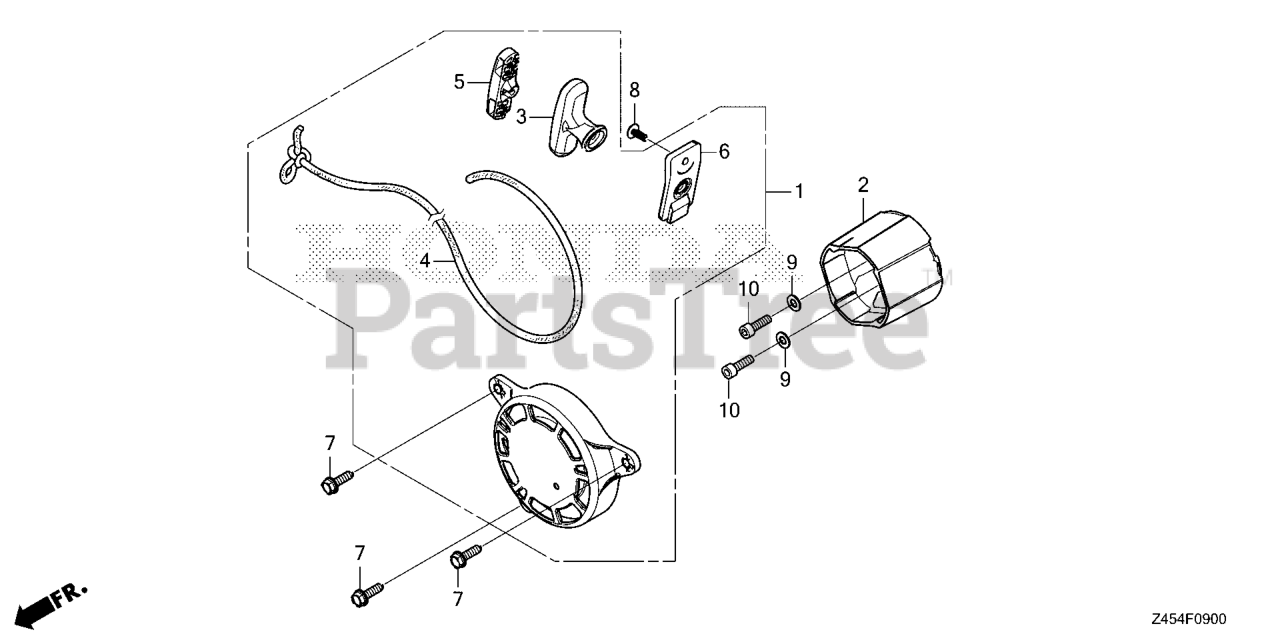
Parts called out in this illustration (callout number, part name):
1	STARTER, RECOIL
3	GRIP, STARTER
4	ROPE, RECOIL STARTER
5	COVER, GRIP
6	GUIDE COMP
7	BOLT, FLANGE (6X20) (CT200)
8	SCREW, TAPPING (5X14) (PO)
9	WASHER, PLAIN (6MM)
10	BOLT, SOCKET (6X20)
